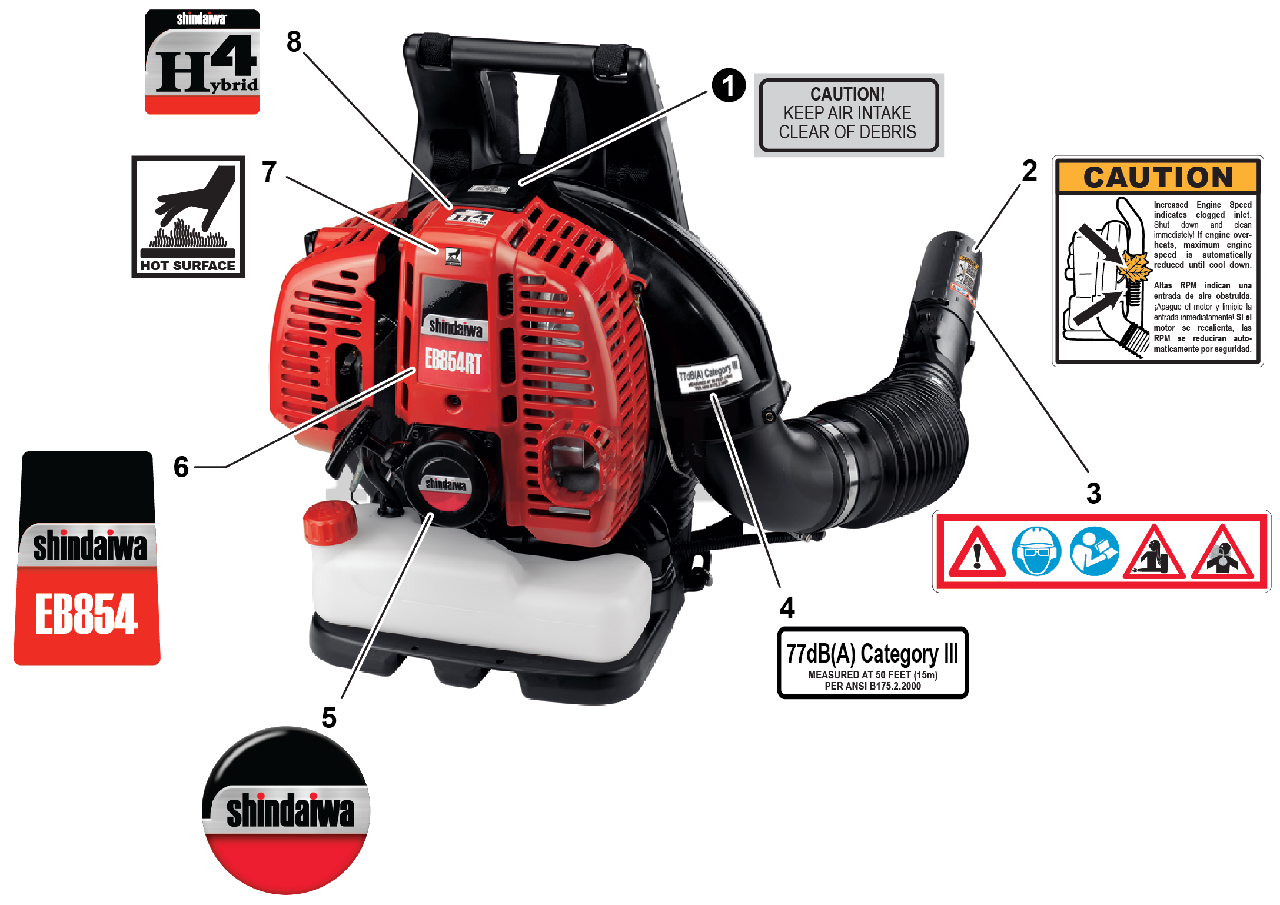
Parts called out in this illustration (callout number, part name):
1	LABEL, CAUTION - AIR INTAKE
2	LABEL, CAUTION - CLOGGED INLET
3	LABEL, CAUTION
4	LABEL, NOISE 77DB(A)
5	LABEL, RECOIL STARTER
6	LABEL - MODEL EB854
7	LABEL, CAUTION - HOT
8	LABEL, SHINDAIWA H4
